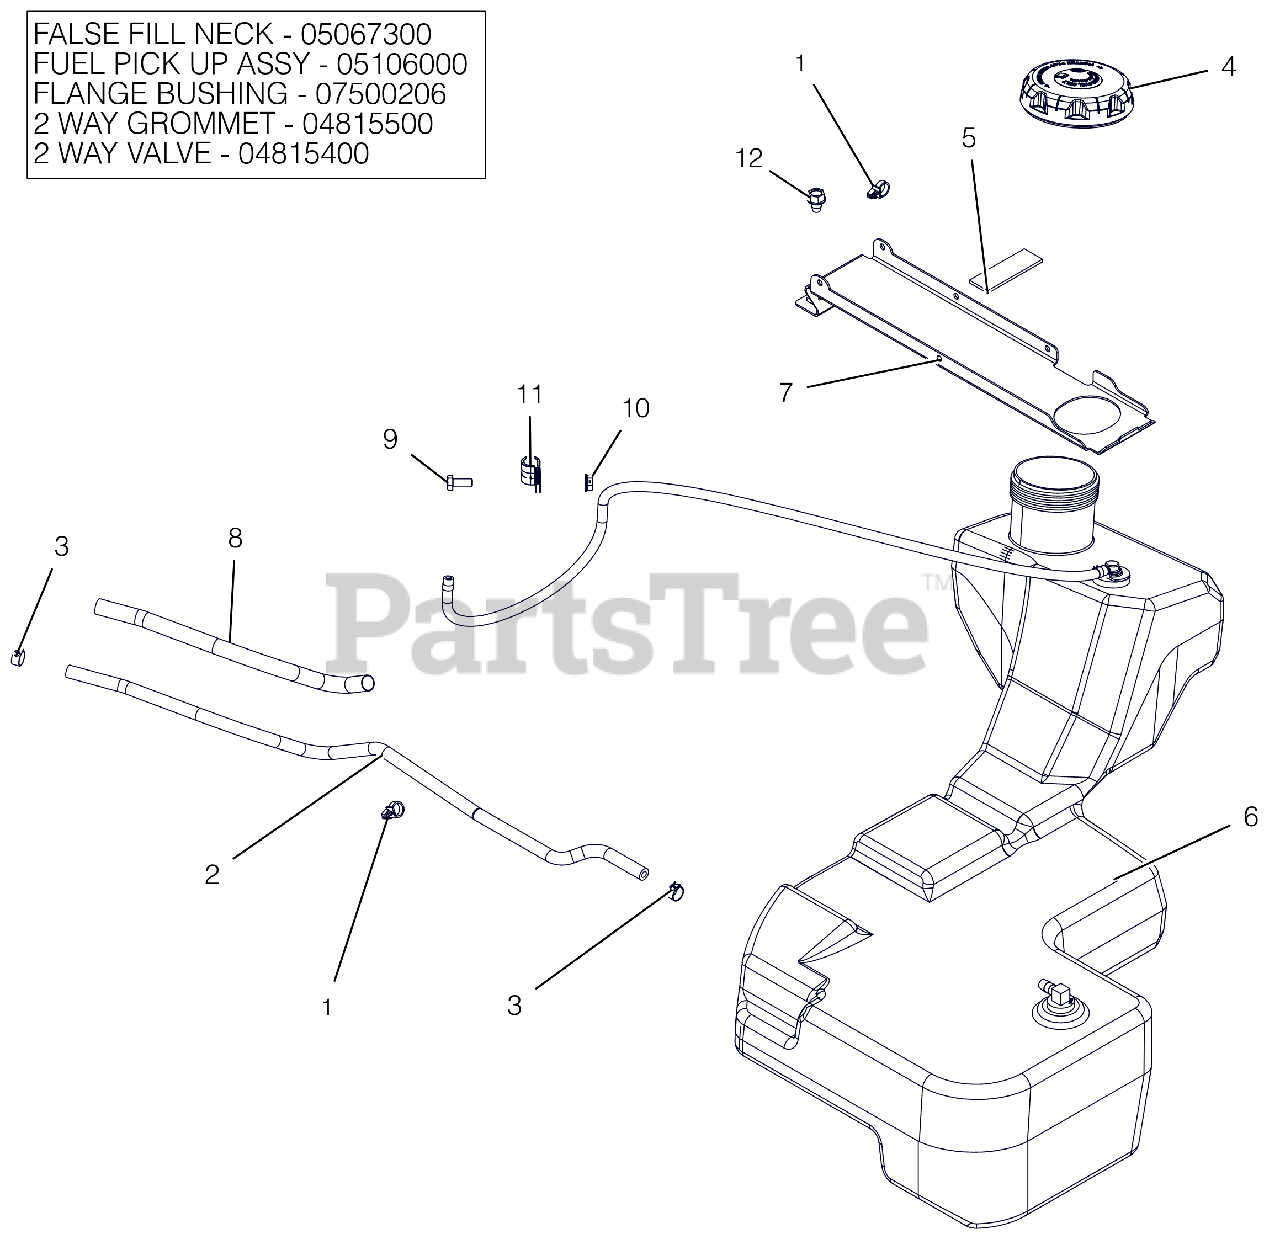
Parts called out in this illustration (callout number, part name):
1	ROUTING CLIP (1/2" ID)
2	HOSE, .25 LOW-PERM BULK GAS
3	CLAMP, FUEL LINE
4	CAP, FUEL VENTIN AUTOLOCK
5	PAD,RBR 1.0"X3.0" W/ADHESIVE
6	ASM, HD FUEL TANK
6	INSERT, FUEL NECK FALSE FILL
6	ASM, HD FUEL PICK-UP
6	BSHG-FLG .375X1.062X.625 NITR
6	GROMMET, 2-WAY
6	VALVE, 2-WAY
7	BRKT, FUEL TANK HOLD DOWN
8	SLEEVE, THERMAL 12"
9	@BLT-HEX .31-18X.75 GR5 YWZC
10	@NUT-LK-CTR-FLG .31-18 YZ GR F
11	CLAMP, CUSHIONED STEEL
12	@SCR-TAP .38-16X.50 HWH TR YWZ
